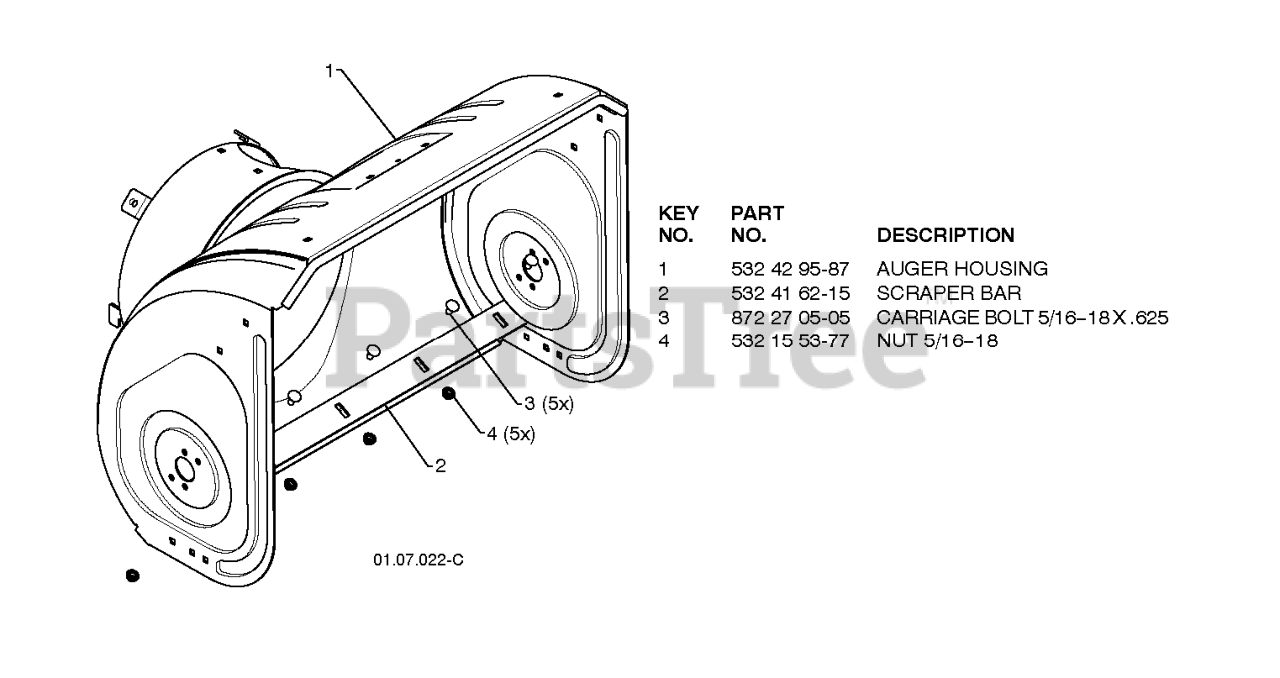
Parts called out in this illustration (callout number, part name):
1	HOUSING.AUG.WELDMENT.27.ORANGE
2	BAR, SCRAPER
3	BOLT
4	NUT.FLANGE.5/16
